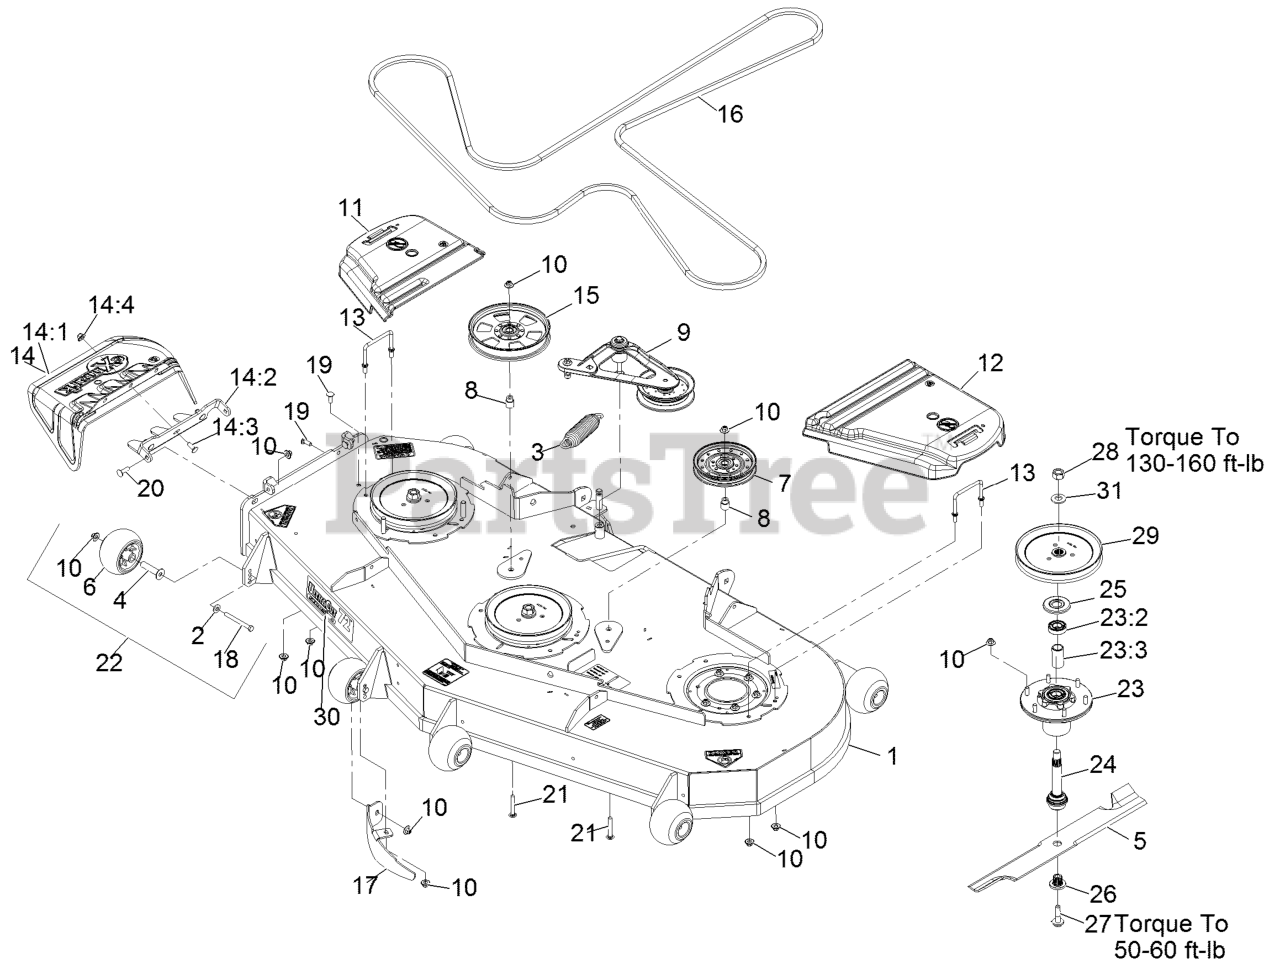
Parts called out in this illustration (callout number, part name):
1	ASM,DECK W/DECALS 724
2	WASHER-BELLEVILLE
3	SPRING-EXTENSION
4	AXLE, ROLLER
6	ROLLER-SCALP, ANTI
8	BUSHING-IDLER
9	DECK IDLER ASM
10	Nut-Nyloc 3/8-16 Flg
11	COVER-BELT, RH
12	COVER-BELT, LH
13	WIREFORM-COVER
14	ASM,DISCHARGE CHUTE
14:1	CHUTE,DISCHARGE
14:2	BRACKET,DISCHARGE CHUTE
14:3	SCREW-CARR
14:4	Nut-Nyloc 3/8-16 Flg
15	PULLEY-IDLER, FLAT
16	BELT-V
17	BAFFLE-DOGLEG, LZ72
18	SCREW-HH 3/8-16 X 3 3/4 GR 8
19	SCREW-CARR
20	Bolt-Carriage 3/8-16 X 1 1/4
21	SCREW-CARR
22	KIT, ANTI-SCALP ROLLER
23	ASM-CUTTER HSG WITH BEARINGS
23:2	BEARING-BALL
23:3	SPACER-BEARING
24	ASM-SPINDLE AND SEAL
25	GUARD,BEARING TOP .989
26	BUSHING,SPLINED
27	SCREW,SEMS 1/2-20 X 2.19
28	NUT-HEX
29	SHEAVE,BLADE DRIVE 8.74
30	DECAL,ULTRACUT 72 SERIES
